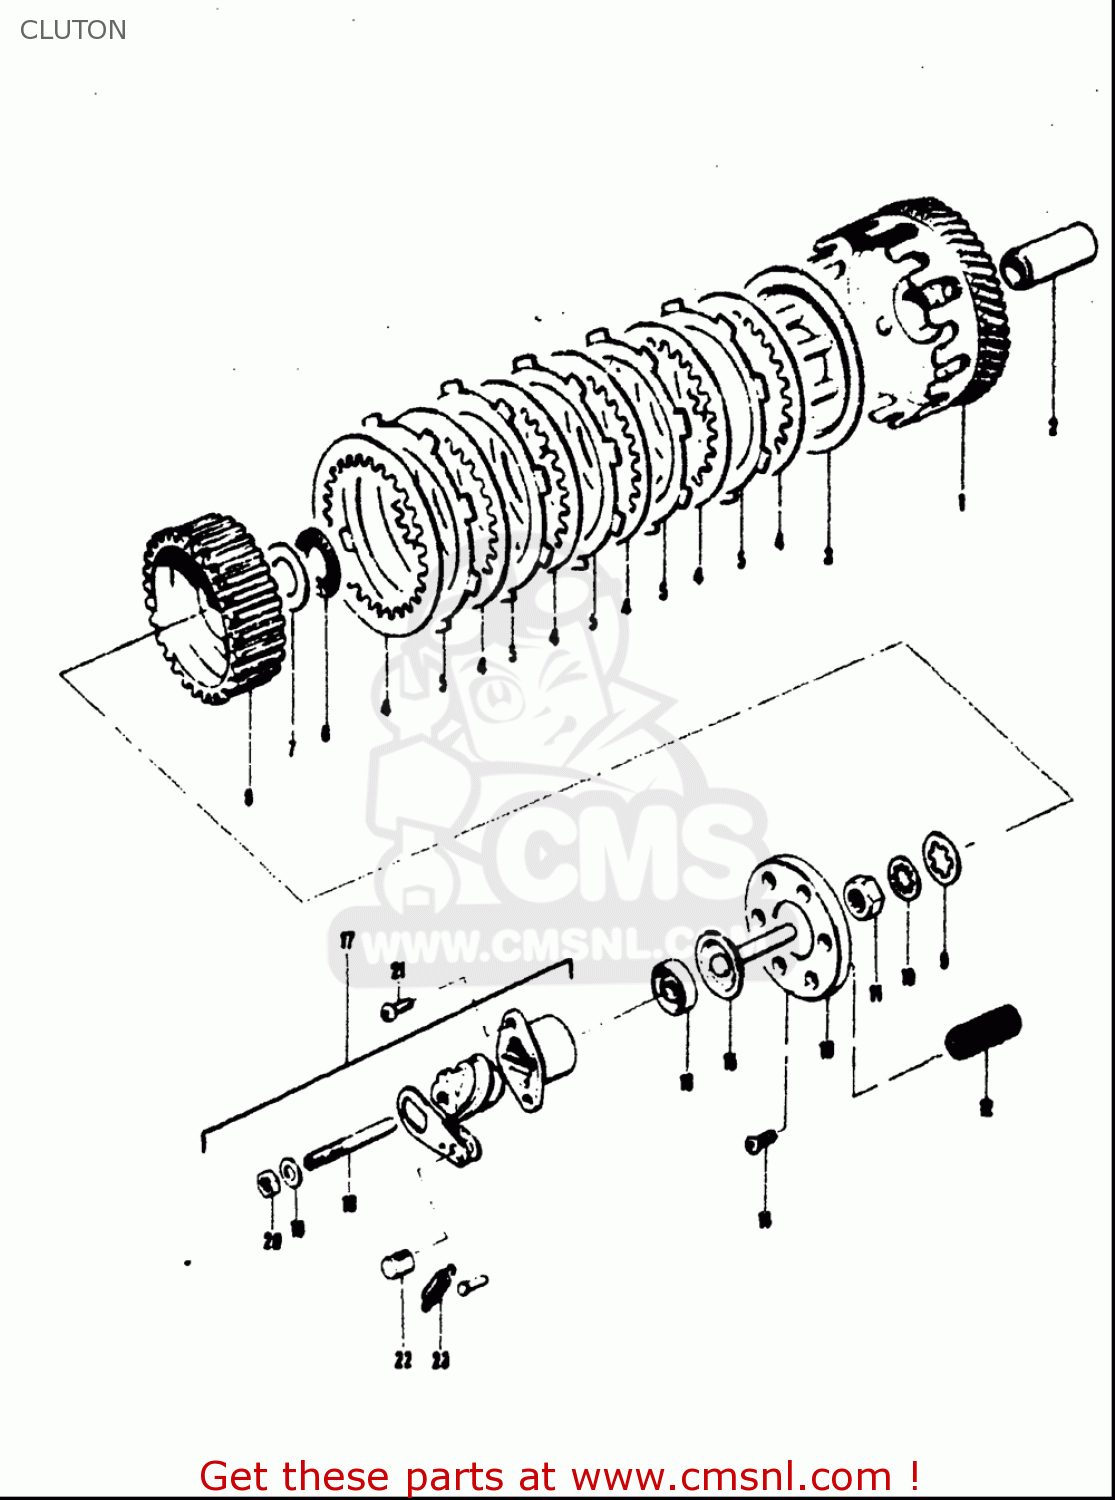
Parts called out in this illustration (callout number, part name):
3	PLATE,CLUTCH PRESSURE
4	PLATE,CLUTCH DRIVEN (NAS)
5	PLATE,CLUTCH DRIVE (NAS)
6	BEARING(20.1X35X2.8)
7	WASHER
8	HUB,CLUTCH SLEEVE
9	WASHER,LOCK
10	WASHER,LOCK
11	NUT
12	SPRING
18	SCREW(6X47.5)
19	WASHER(6.5X16X1.2)
20	NUT
21	SCREW(5X14)
22	PIECE,RELEASE ARM END
23	SPRING
